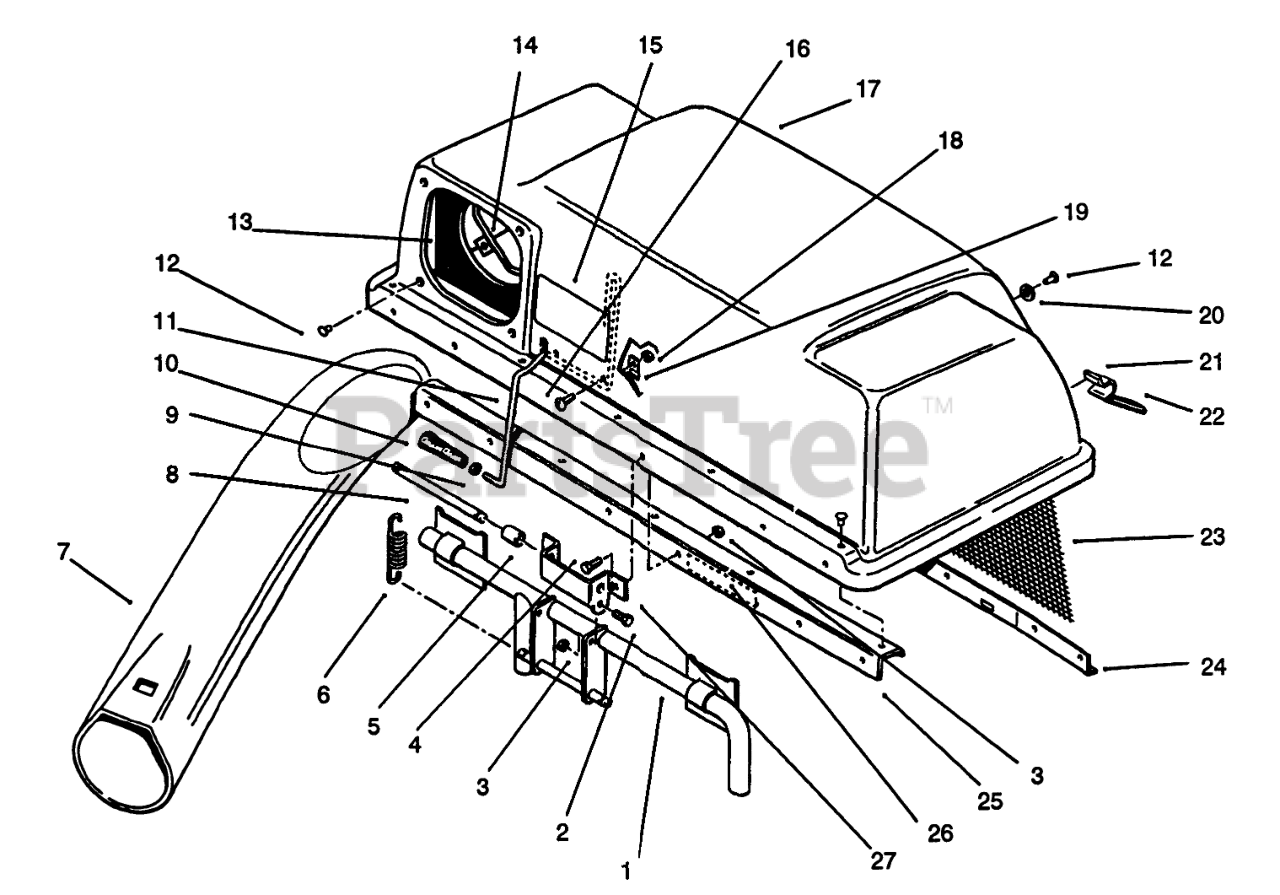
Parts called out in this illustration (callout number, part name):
1	FRAME ASM
2	Bolt
3	NUT-LOCK, NI
4	BOLT
5	SPACER
6	SPRING-EXTENSION
7	CHUTE-BAGGER
8	PIN-SPRING
9	NUT-JAM
10	HANDLE-TAPERED
11	FEELER-FILL, BAG
12	RIVET-BLIND
13	SEAL-CHUTE
14	CLAMP-SEAL
15	DECAL
16	Screw
17	TOP-BAGGER
18	NUT-LOCK, NI
19	Clip
20	Washer
21	Latch-Bag
23	SCREEN-BAGGER
24	Screen Support
25	Bagger-Stiffener
26	DECAL-CAUTION
27	HINGE-BAG TOPB
